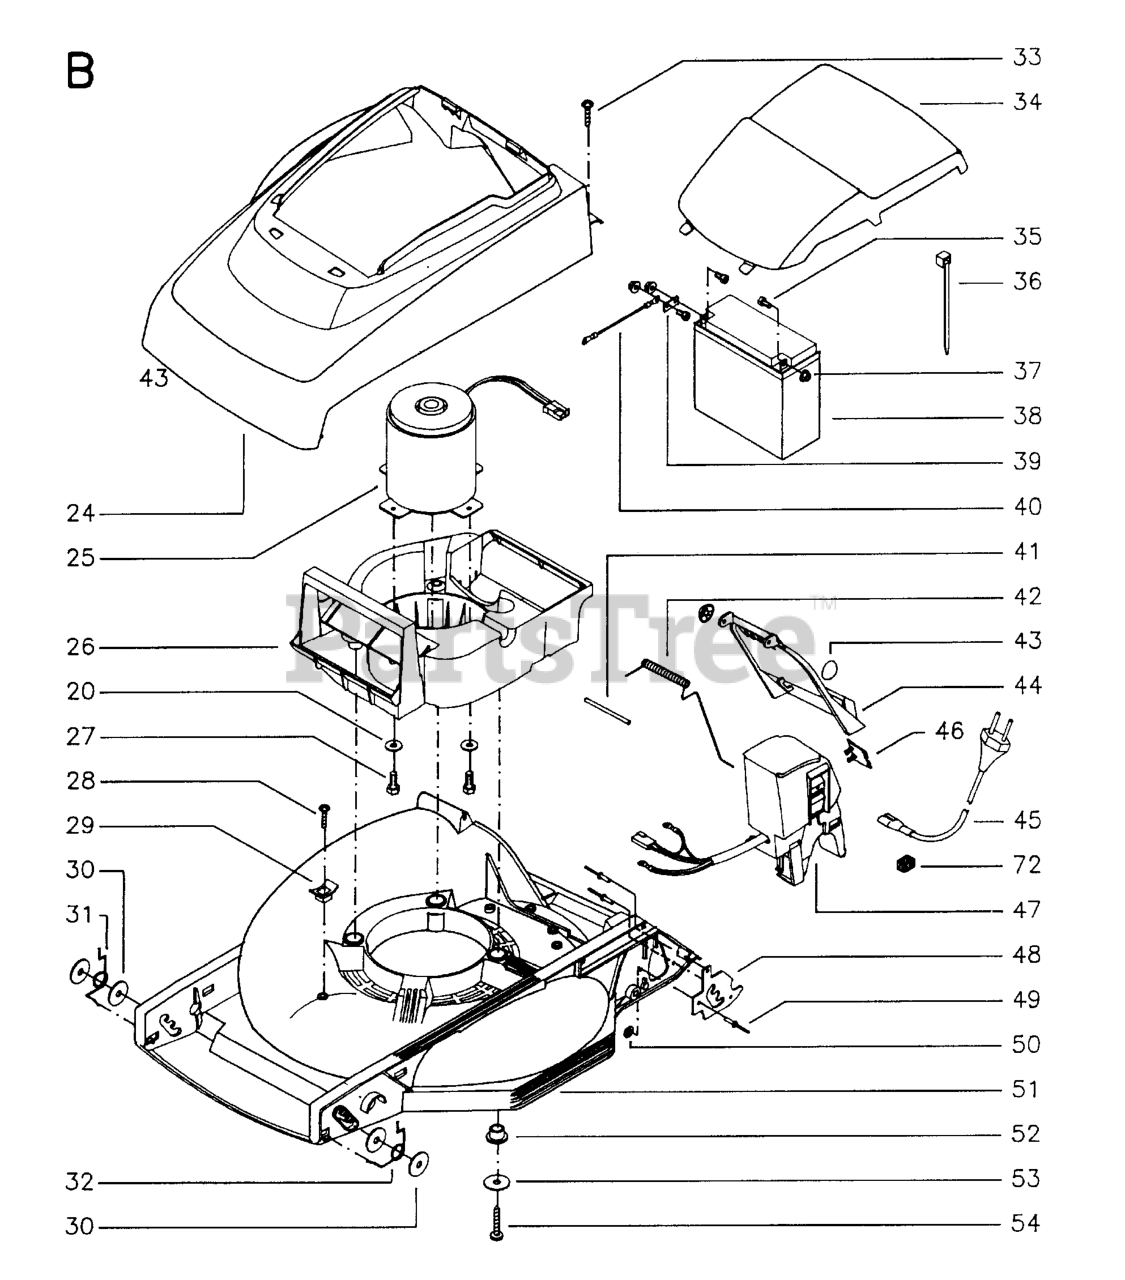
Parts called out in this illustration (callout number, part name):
30	Washer, Flat 1-1/2" x .375" x .062"
33	SCREW
41	PIN
50	WASHER
